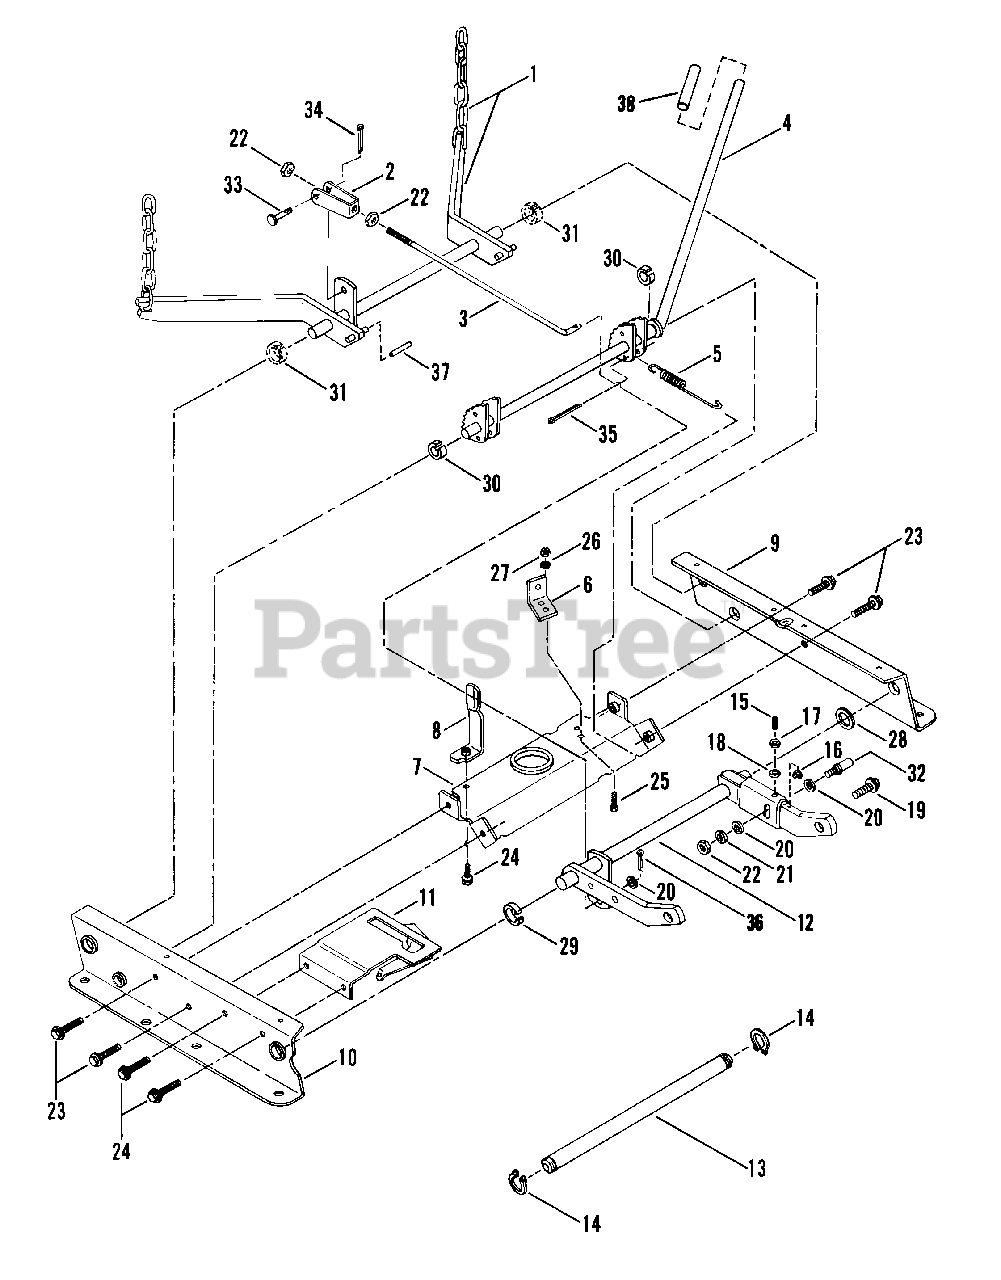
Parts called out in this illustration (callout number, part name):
1	REAR LIFT ARM ASSY
2	CLEVIS, Timing Rod
3	TIMING ROD
4	CAM LIFT LEVER
5	SPRING, Cam Lift
6	ANCHOR
7	BRACE, Top
8	GUIDE, Belt
9	RAIL, Left Hand
10	RAIL, Right Hand
11	ASSEMBLY CLUTCH-PLATE
12	FRONT LIFT ARM
13	SUPPORT ROD
14	RING, 5/8" External Retaining
15	SETSCREW, 5/16-18x1 1/4" Hex Socket
16	NUT, 5/16-18 Hex
17	JAM-NUT, 5/16-18 Hex
18	WASHER, 5/16 SAE
19	CAPSCREW, 3/8-24x1 1/4" Hex Head
20	WASHER, 3/8 SAE
21	LOCKWASHER, 3/8 Split
22	NUT, 3/8-24 Hex
23	SCREW, 3/8-16x1" Hex Self-Tap
24	SCREW, 5/16-18x5/8" Hex Self-Tap
25	SCREW, 5/16Fx3/4" Hex Head Cap
26	LOCKWASHER, 5/16 Internal Tooth
27	NUT, 5/16F Hex
28	WASHER
29	RING, Red
30	RING, White
31	RING, Blue
32	PIN, Shoulder Bolt
33	PIN, 3/8 x 1 1/16" Clevis
34	PIN, 3/32x3/4" Cotter
35	PIN, 5/32x1" Cotter
36	PIN, 1/8x3/4" Cotter
37	PIN, Roll
38	GRIP, Height Adjustment Lever
